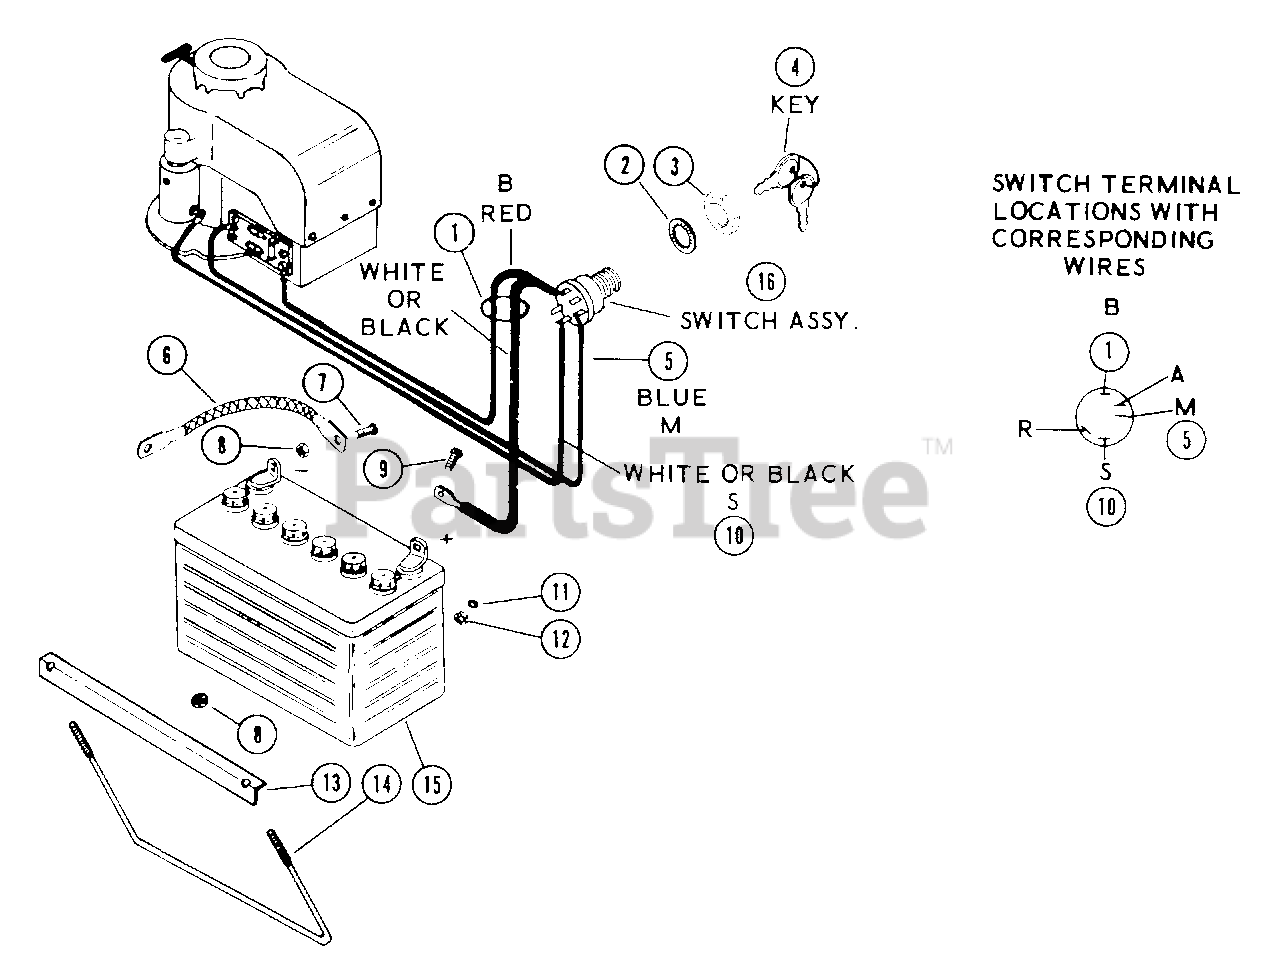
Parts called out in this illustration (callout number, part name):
1	POSITIVE BATTERY CABLE
2	WSHR-LK-INT .625X.045 PL
3	NUT .625-32 ALUM
4	KEYS
5	ENG SHORTING WIRE
6	GROUND CABLE
7	BLT-HEX .25-20X.63 PL GR2
8	NUT-LK-FLG .250-20 PL
9	BLT-RDHDSQNK .31-18X.75 GR5 PL
11	WSHR-LK .312X.097 PL HVY
12	NUT-HEX .312-18
13	BATTERY HOLD DOWN
14	BATTERY CLAMP
15	BATTERY
16	IGNITION SWITCH ASSEMBLY
